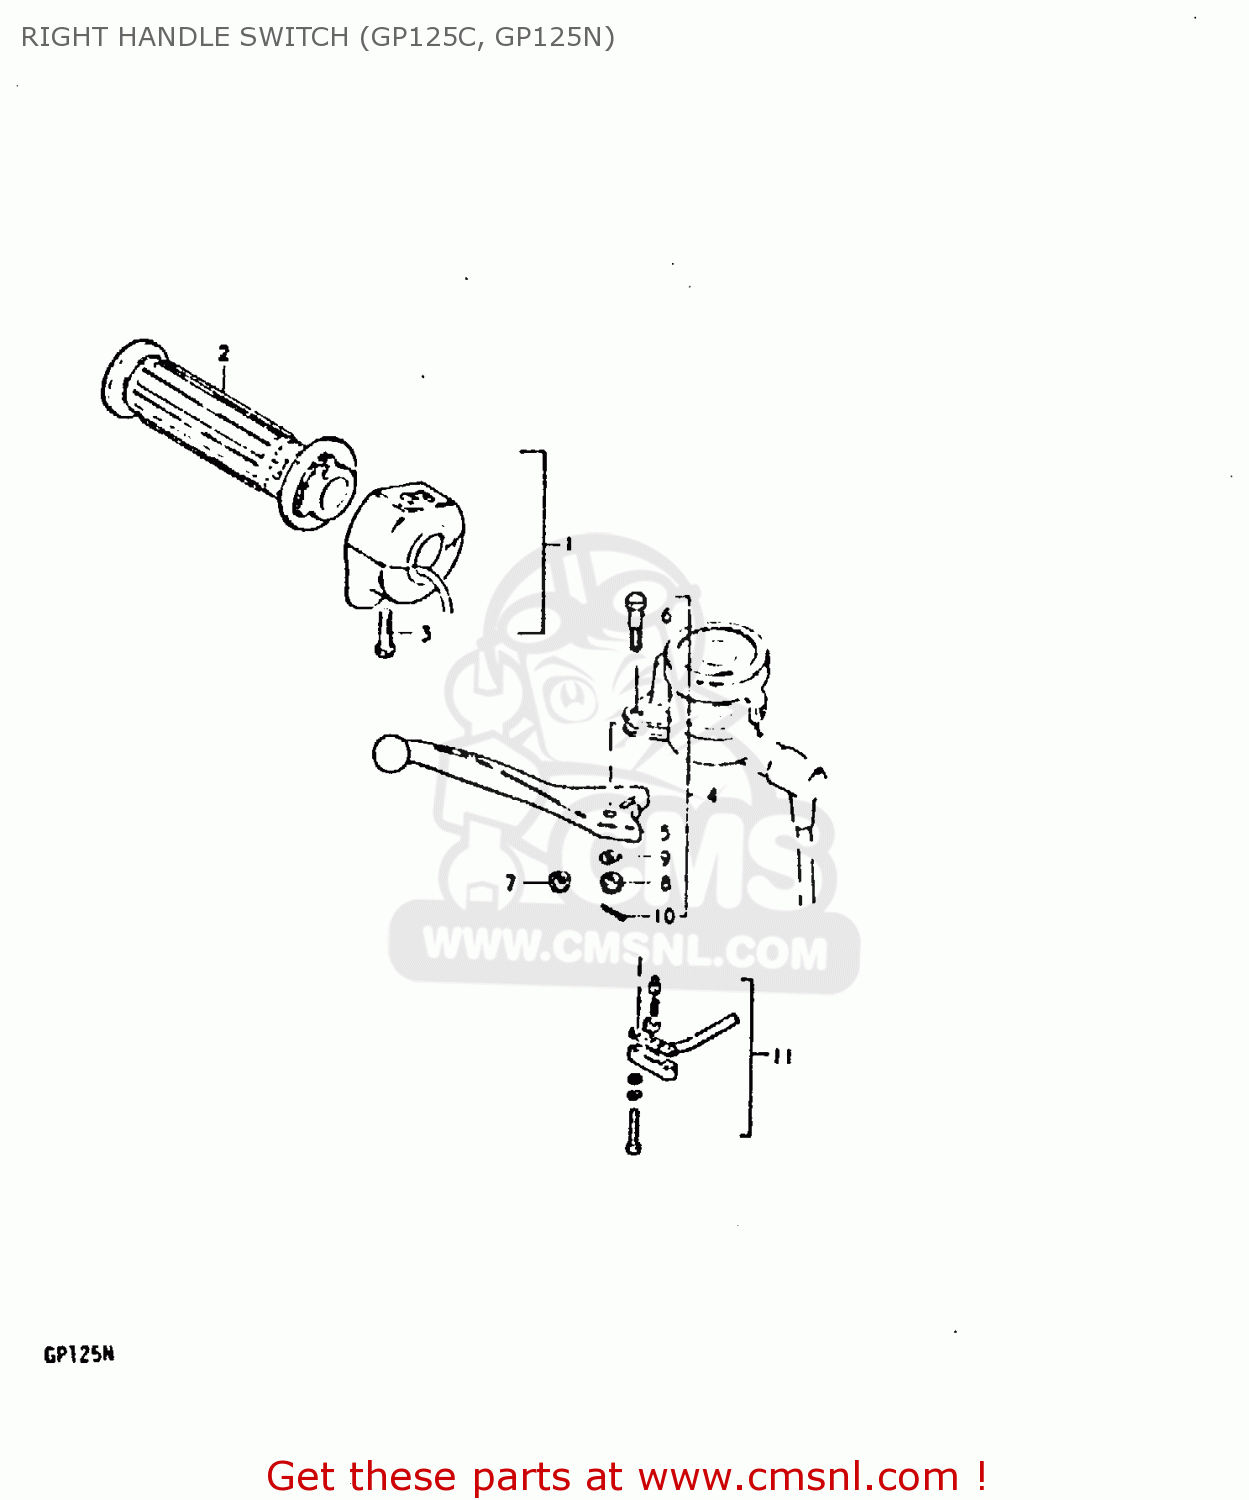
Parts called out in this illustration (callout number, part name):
1	GRIP ASSY, THROTTLE
2	GRIP,THROTTLE
3	SCREW
4	LEVER ASSEMBLY,BRAKE
5	LEVER,BRAKE
6	BOLT
7	NUT 6MM
8	NUT,LEVER FITTNG
9	LOCK WASHER
10	COTTER PIN
